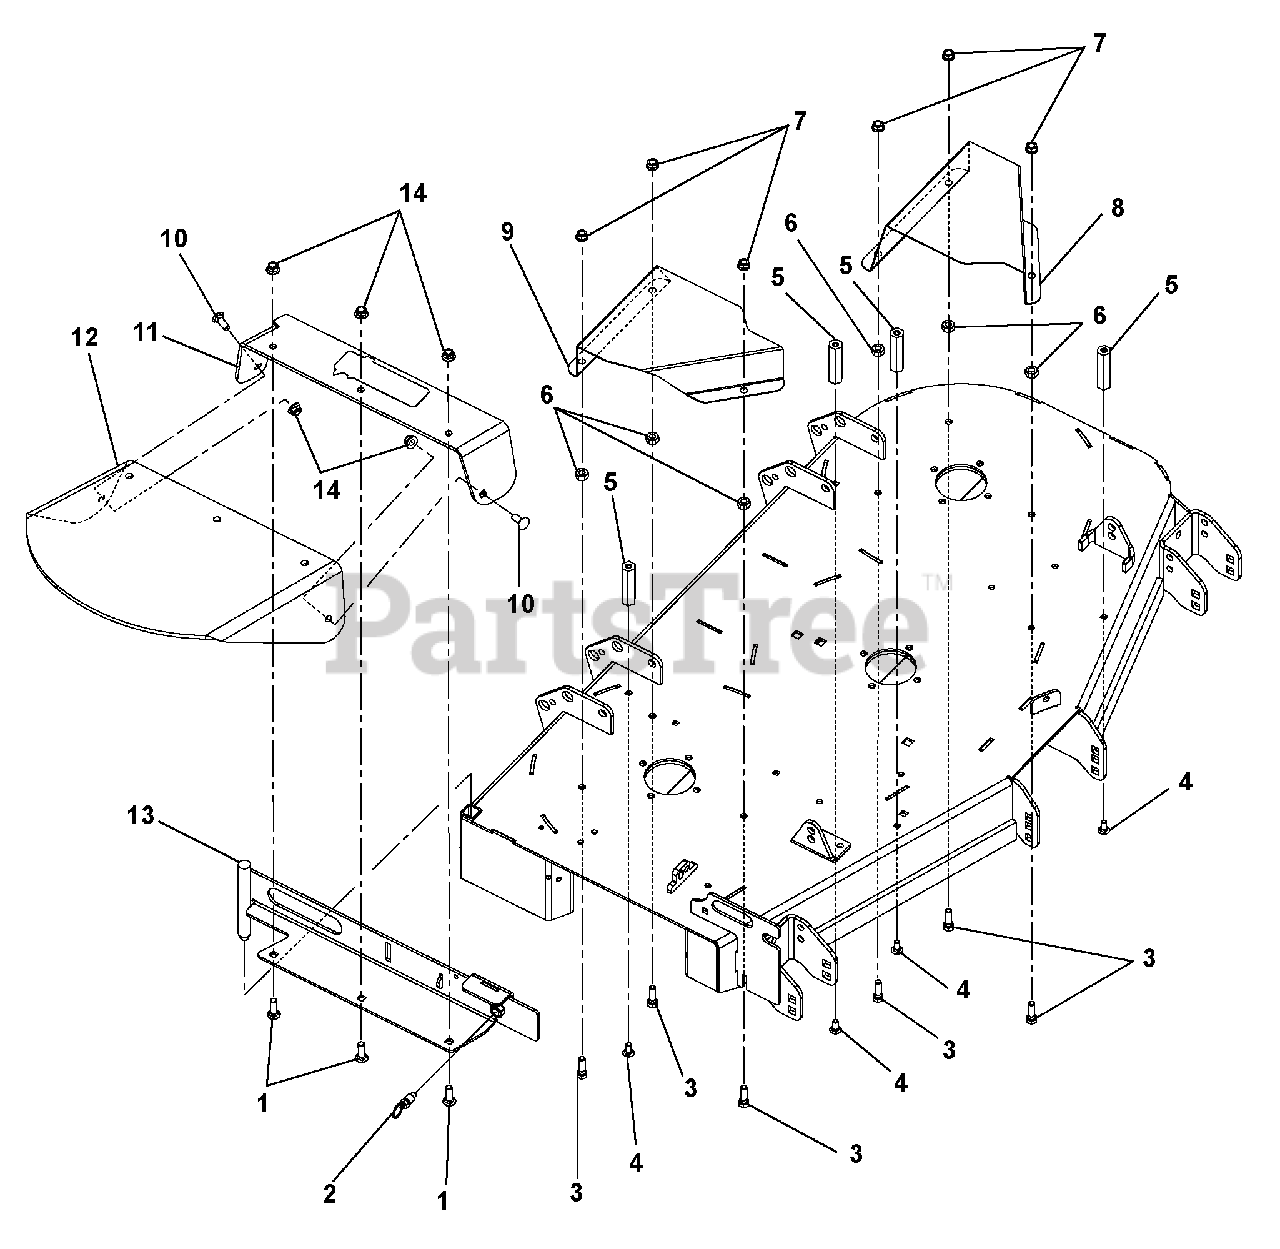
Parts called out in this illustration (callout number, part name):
1	Bolt, Round Head Square Neck .38-16 x 1.25 Grade 5
2	Pull Pin
3	Bolt, Hex .38-16 x 1.25 Grade 5
4	Bolt, Round Head Square Neck .31-18 x .75
5	Nut, Coupling .31-18 x 3.00
6	Nut, Heavy Hex .38-16
7	Nut, Flange .375-16
8	Guard, 44-52 Left Hand Spindle Sheave (062, 063)
9	Guard, 44-52 Right Hand Spindle Sheave (062, 063)
10	Bolt, Round Head Square Neck .38-16 x 1.00 Grade 5
11	Rubber Discharge Chute Support
12	Chute, Rubber Discharge
13	Weldment, 48" Discharge Chute Support (062)
14	Nut, .38-16 Nyloc Flange
